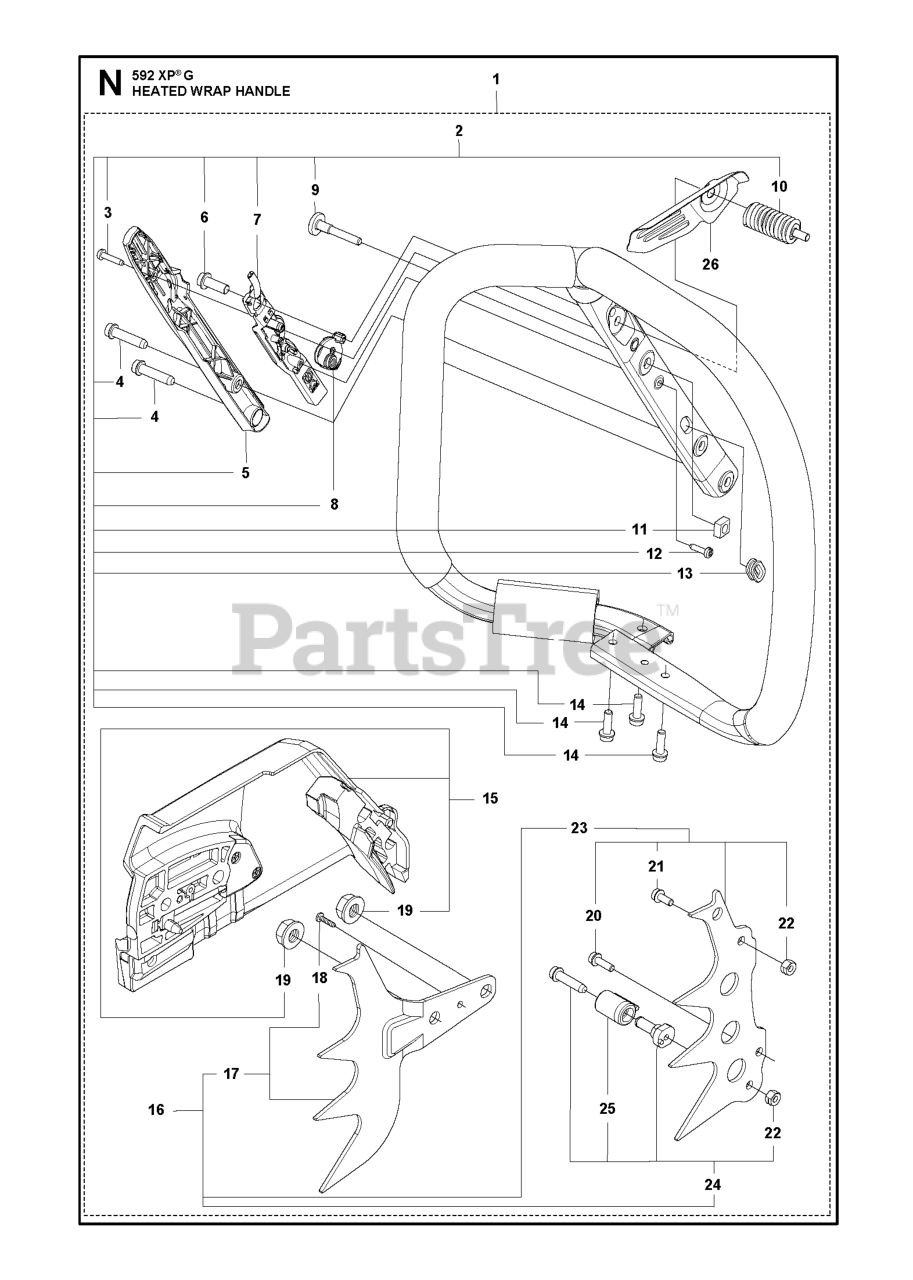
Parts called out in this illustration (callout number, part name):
1	WRAP KIT WITH COVER
2	HANDLE SYSTEM WRAP XPG
3	SCREW CITXPANT HEXABULAR SOCKE
5	COVER FRONT HANDLE HEAT
6	SCREW ITXSCFM
7	CONTACT PLATE FRONT HANDLE HE
9	SCREW ITXPANM MOVEMENT LIMITER
10	ANTIVIBRATION ELEMENT CYLINDE
12	SCREW CITXPANT
15	Covers
16	SPIKE KIT WRAP
17	SPIKE KIT OUTER WRAP
18	SCREW CITXPANT
19	NUT M8 FLANGE
21	SCREW
23	SPIKE KIT INNER WRAP
24	CHAIN CATCHER H565/H572 KIT
